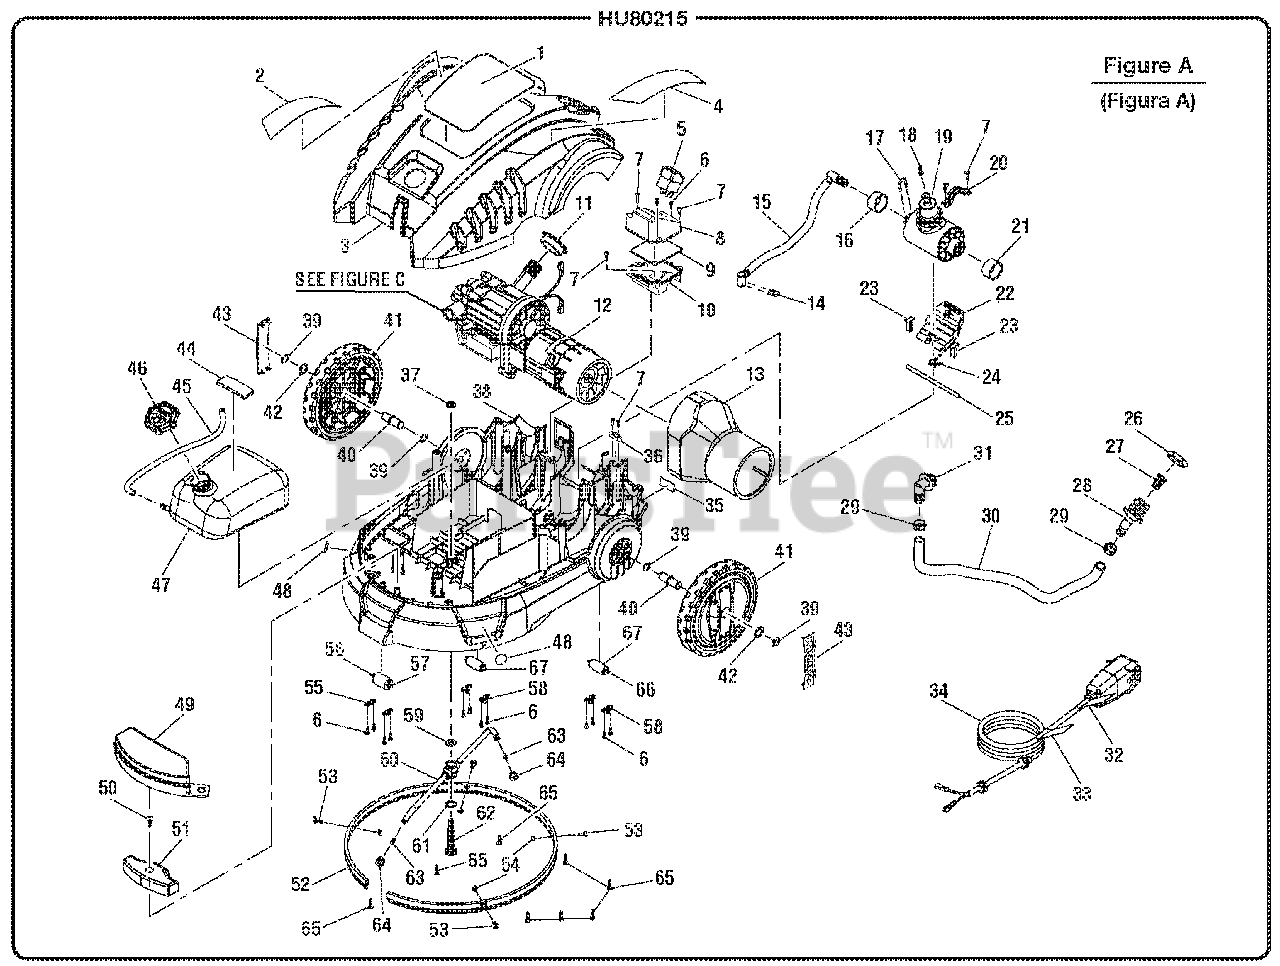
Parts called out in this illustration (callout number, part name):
1	Performance Label
2	Quick Start Label
3	Top Housing Assembly (Incl. Key Nos. 1-2 & 4)
4	Warning Label (ENG)
6	Screw (M3.5 x 12 mm)
7	Screw (M4.2 x 15 mm)
8	Switch Box Cover
9	Switch Box Gasket
10	Switch Box
11	Pump Outlet Ring
12	Motor and Pump Assembly
13	Motor Baffle
14	U pin (2.5 mm)
15	High Pressure Hose Assembly
16	Left Pivot Bushing
17	U pin (3 mm)
18	Nipple Filter
20	Pivot Clamp
21	Right Pivot Bushing
22	Foot Pedal
23	Bearing Block
24	Torsion Spring
25	Foot Pedal Shaft
26	Inlet Nut
27	Inlet Filter
28	Inlet Connector
29	Hose Clamp
30	Inlet Hose
31	Pump Inlet Connector Assembly
32	Propsition 65 Label (CA)
33	Warning Label (UL)
34	Power Cord Assembly (Incl. Key Nos. 32-33)
35	Data Label
36	Cord Clamp
37	Spindle Nut (M10)
38	Lower Housing Assembly (Incl. Key Nos. 35 &48)
39	Retaining Ring
40	Wheel Axle
41	Wheel Assembly
43	Wheel Logo
44	Detergent Tank Pad
45	Detergent Hose
46	Detergent Tank Cap
47	Detergent Tank
48	Foot/Hand Caution Label
49	Lift Handle
50	Screw (M4 × 16 mm)
51	Balast Weight
53	Screw (M4 x 12 mm)
54	Lock Nut (M4)
55	Front Roller Clamp
56	Front Roller Axle
57	Front Roller
58	Rear Roller Clamp
59	Upper Spinner Bushing
60	Spinner Assembly
61	Lower Spinner Bushing
62	Spindle Assembly
63	Spinner Nozzle Assembly
64	Spinner Nozzle Holder
65	Screw (M4.2 × 18 mm)
66	Rear Roller Axle
67	Rear Roller
